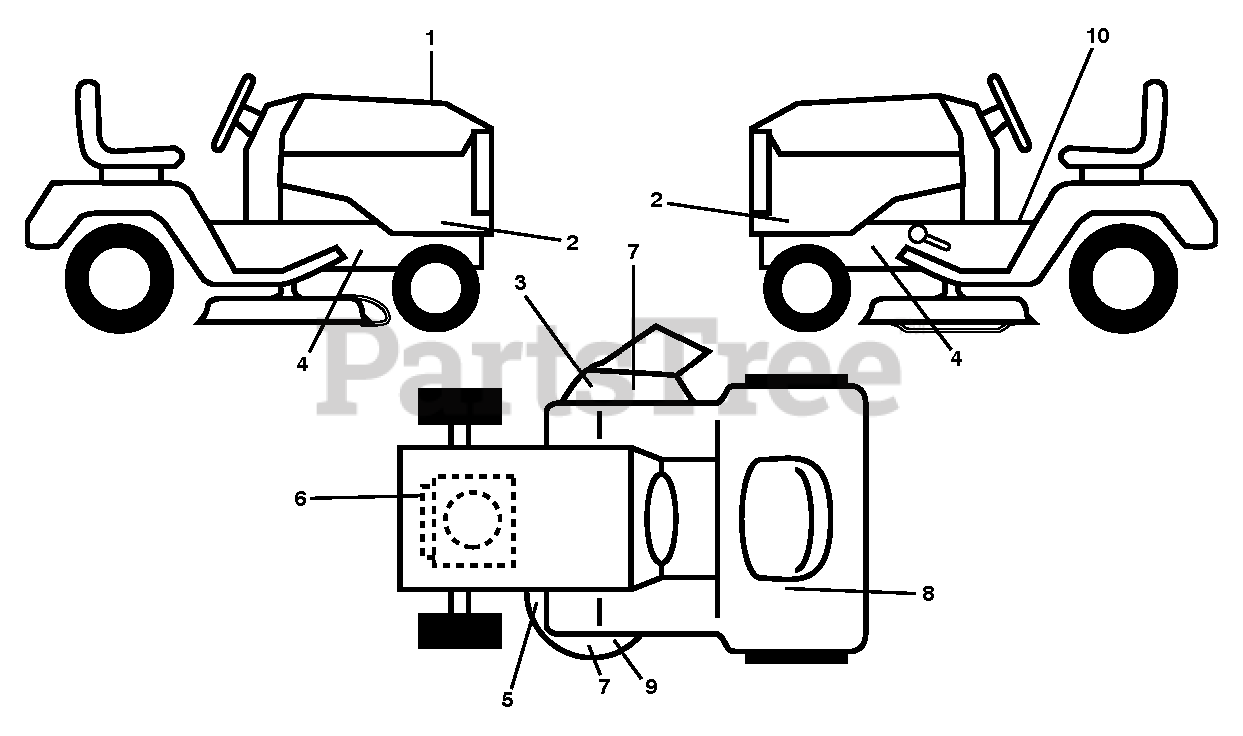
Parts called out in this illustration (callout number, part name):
1	DECAL.RPL.KAW.FR.TLB.48F.K46L
3	DECAL.TRACT/ZTR.DECKWARN.HUSQ
4	DECAL.WARNING.HOT.MUFFLER.2021
4	DECAL.CHASSIS.HOT.MUFFLER
5	DECAL.MOWER.SCH.48/54.PREM
5	DECAL.DECK.BELT.ROUTING.48/54
6	DECAL.ENGINE.WARNING
7	DECAL.DECK.CLEARCUT.NOSTEP
9	DECAL DECK DECAL DECAL.48DECK.
10	DECAL.TRACTOR.SADDLE
